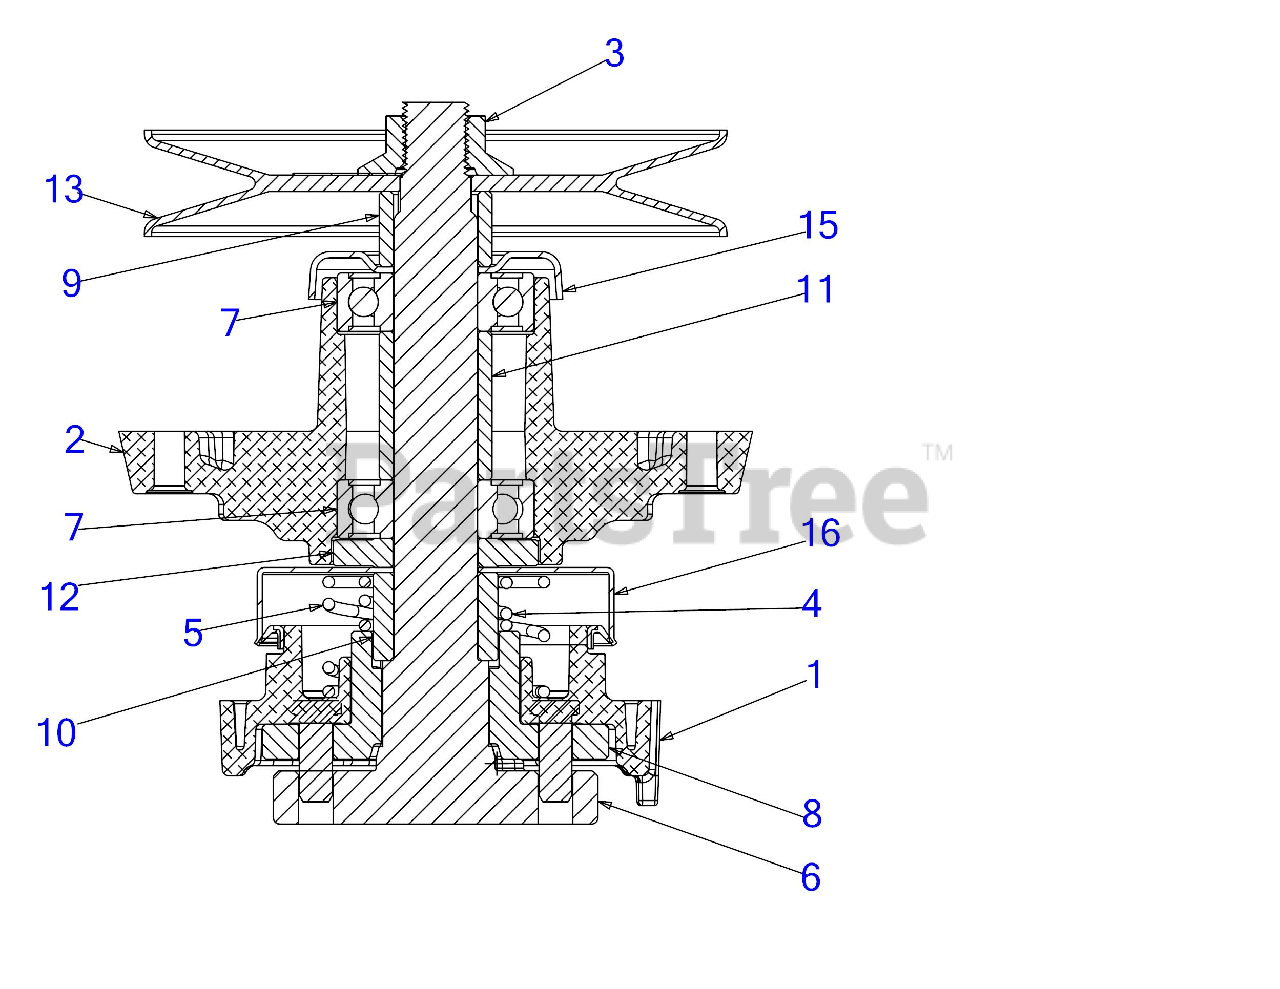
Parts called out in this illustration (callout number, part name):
1	SPINDLE COLLAR ASSEMBLY
2	SPINDLE HOUSING
3	FLANGE NUT 5/8-18
4	COMPRESSION SPRING
5	COMPRESSION SPRING
6	SPINDLE SHAFT
7	BALL BEARING
8	BLADE ADAPTER
9	PULLEY SPACER
10	SPACER
11	BEARING SPACER
12	SPINDLE SHIELD
13	SPINDLE PULLEY 5.57" DIA
15	SHIELD-BRG DECK
16	SEAL CAP
